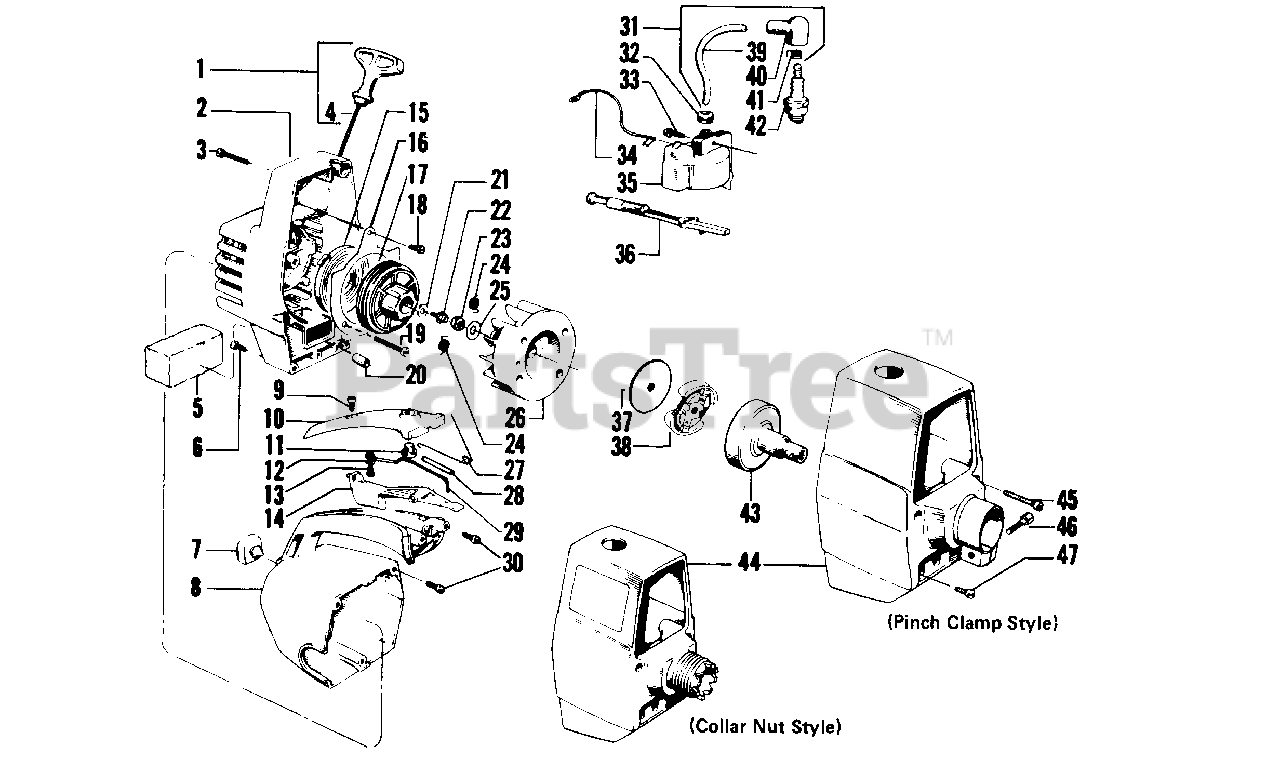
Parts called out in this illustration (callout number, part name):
2	Fan Housing (Inc. 16, 18, 19, 20 & 28)
3	Screw - #10 - 24 x 1-1/2" Fan Housing - Top
4	Rope (3.5 ft.)
5	Air Filter
6	Screw - #10 - 24 x 5/8" Fan Housing - Bottom
7	Bumper - Fuel Tank Housing
8	Handle and Fuel Tank Housing
9	Screw - #8 - 16 x 3/4" - Pan Hd. Handle Cover
10	Handle Cover
11	Button - Kill Switch
12	Washer - Kill Switch
13	Screw - #8 - 16 x 3/8" - Pan Head - Kill Switch
14	Trigger - Throttle
16	Air Baffle
18	Screw - #10 x 1/4" - Fil. Hd. - Air Baffle
19	Screw - #10 - 24 x 1-3/16" - Fil. Hd.
21	Washer #10 - Starter Pulley
22	Screw - #10 x 3/4" - Hex Washer Hd. - Starter Pulley
23	Nut - Flywheel - #5/16 x 24" - Fil. Hd.
24	Spring - Starter Dog
25	Washer - Flywheel
26	Flywheel Assembly (Inc. 24)
27	Trigger Spring
28	Insulation - Switch Spring
29	Spring - Kill Switch
30	Screw - #10 - 14 x 3/4" - Pan Head - Fan Hsg. to Handle & Fuel Tank
31	High Tension Lead Assembly (Inc. 39, 40 & 41)
32	Grommet - Plug Wire
33	Screw - #8 - 32 x 3/4" - Fil. Hd. - Ignition Module
34	Lead Wire - Switch
35	Kit - Ignition Module
36	Knob - Choke
37	Kit - Clutch Washer (3/8" Flat) - See Service Ref. 6.
38	Kit - Clutch Ass'y - See Service Ref. 1 & 6.
39	High Tension Lead Wire
40	Boot - Spark Plug
41	Connector - Spark Plug Lead
42	Spark Plug
43	Coupling and Bearing Assembly
44	Shroud
44	Pinch Clamp Style
44	Screw Collar Style
45	Screw - #10 - 24 x 1-1/3" - Fil. Hd. - Shroud (Top)
46	Bolt - Pinch Clamp
47	Screw - #10 - 24 x 5/8" - Fil. Hd. - Shroud (Bottom)
